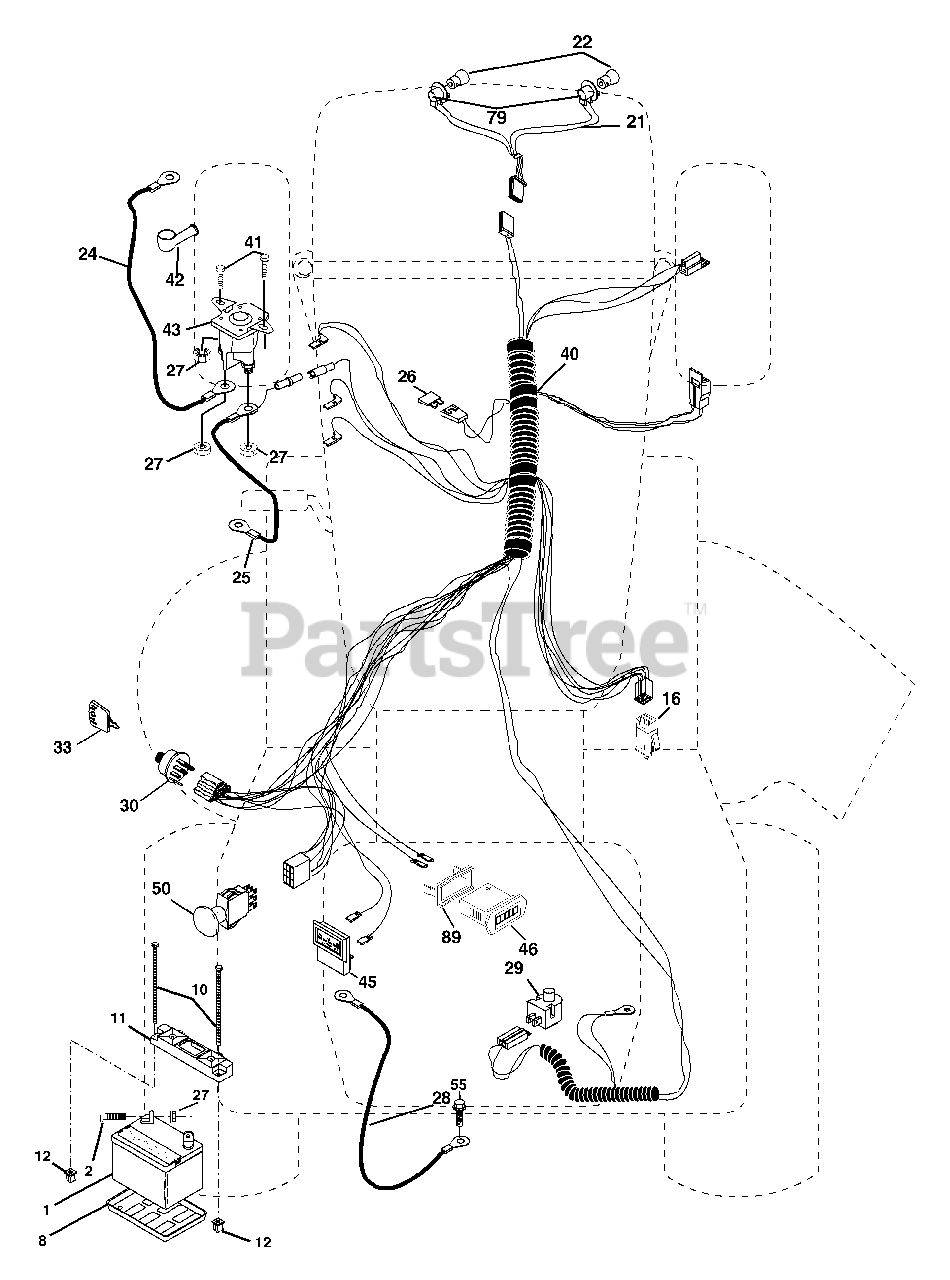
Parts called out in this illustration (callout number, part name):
1	Battery
2	Bolt Hex Hd 1/4-20 unc x 3/4
8	Tray, Battery
10	Bolt, BTR FRT 1/4-20 x 7.5
11	Hold Down Battery, Front
12	Nut, Push, Nylon
16	Switch Interlock Push-In
21	Harness Asm Light W/Bulbs
22	Bulb Light
24	Cable Battery
25	Cable Batterywire
26	Fuse
27	Nut Keps Hex 1/4-20 unc
28	Cable Ground
29	Switch Plunger Normal NC Gray
30	Switch Ign 4 pos w/lights
33	Key Ign
40	Harness Ign.
41	Bolt Blk Fin Hex 1/4-20 x 1/2
42	Cover Terminal Red
43	Solenoid
45	Ammeter Rectangular
46	Hourmeter Snap-In
50	Switch, PTO
55	Screw Thdrol 5/16-18 x 1/2
79	Bulbholder
89	Bracket Snap-In Hourmeter
